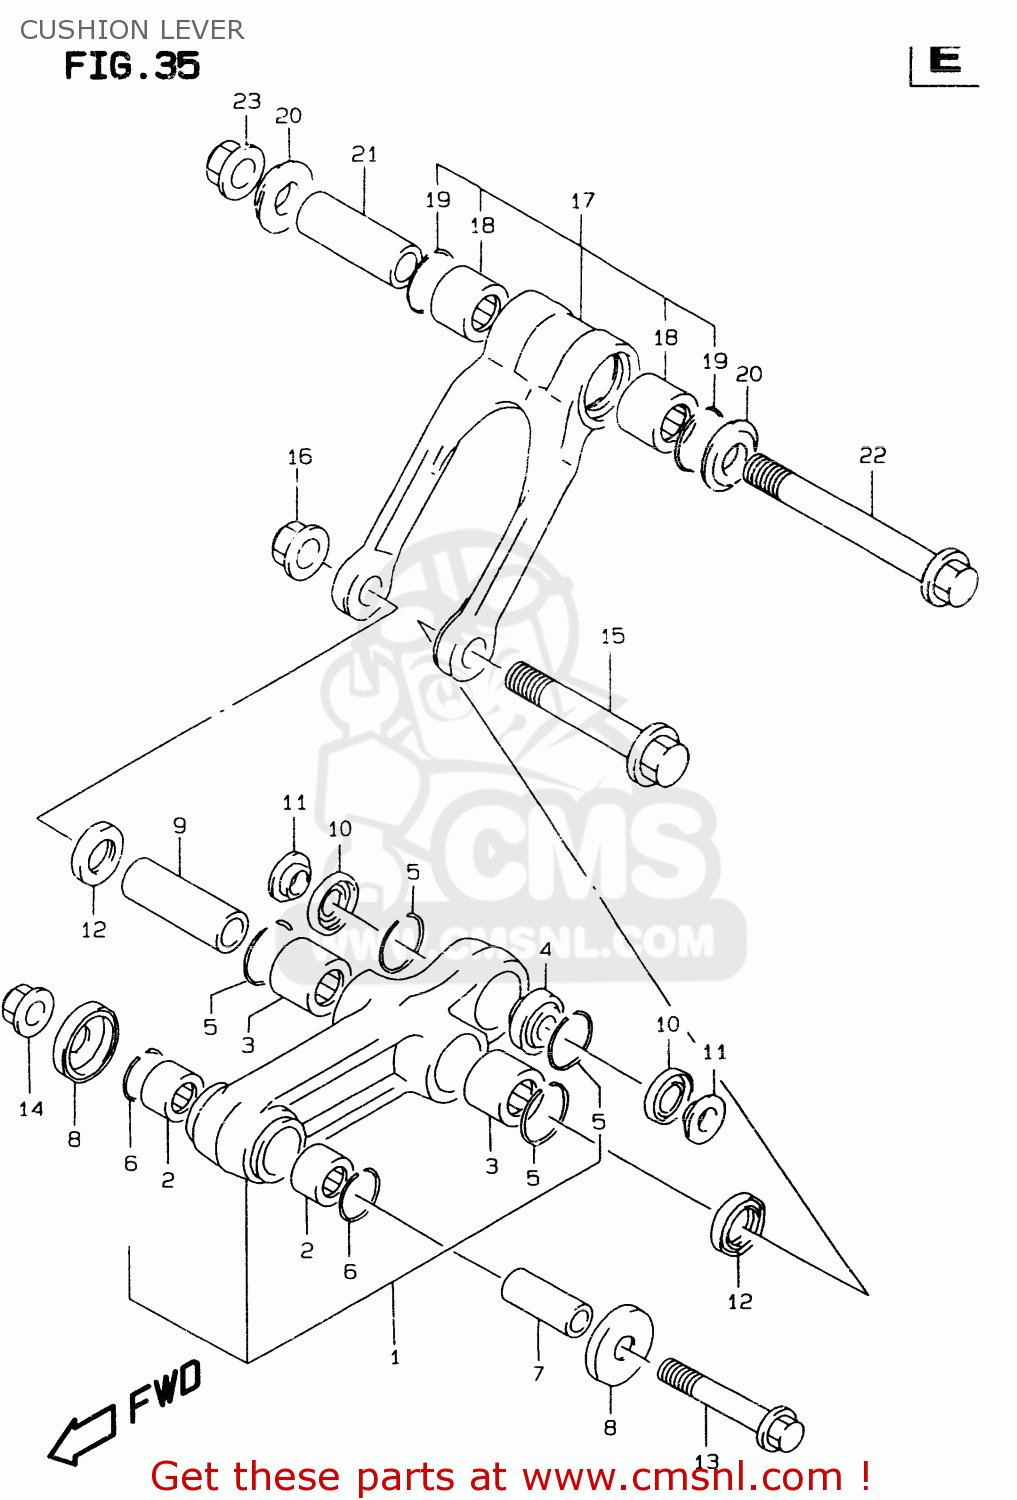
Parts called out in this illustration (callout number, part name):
1	LEVER SET,RR CUSHION
2	BEARING(14X20X12)
3	BEARING(17X24X20)
4	BEARING,RR CUSHION LEVER
5	RING,STOPPER
6	CIRCLIP,PISTON PIN
7	SPACER,RR CUSHION LEVER FR
8	SEAL,RR CUSHION LEVER FR DUST
9	SPACER,RR CUSHION LEVER CTR
10	SEAL,RR CUSHION LEVER RR DUST
11	SPACER,RR CUSHION LEVER RR
12	SEAL,OIL(17X24X3)
13	BOLT,RR CUSHION LEVER FR
14	NUT
15	BOLT,RR CUSHION LEVER CTR
16	NUT 12MM
17	ROD SET,REAR CUSHION,LEFT
18	BEARING(17X24X20)
19	RING,STOPPER
20	SPACER,RR CUSHION ROD SIDE
21	SPACER,RR CUSHION ROD
22	BOLT,RR CUSHION ROD
23	NUT 12MM
